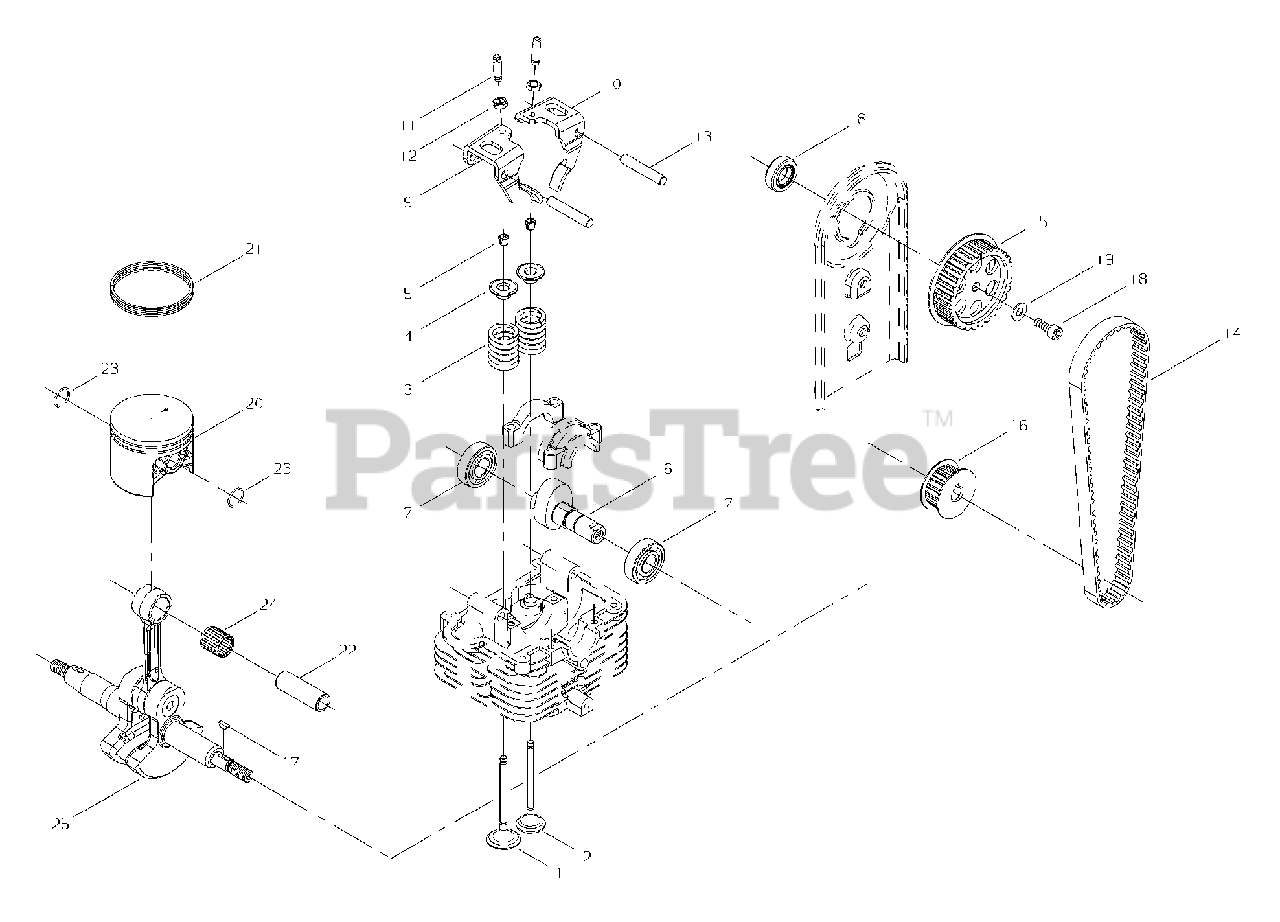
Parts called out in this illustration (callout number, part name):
1	VALVE, INTAKE
2	VALVE, EXHAUST
3	SPRING, VALVE
4	RETAINER, VALVE
5	KEEPER, VALVE
6	CAMSHAFT
7	BEARING, BALL 6001
8	SEAL, OIL 12
9	ARM, ROCKER
10	ARM, ROCKER
11	SCREW, ADJUSTER
12	NUT, ADJUSTER LOCK 5
13	SHAFT, CAM FOLLOWER 6
14	BELT
15	PULLEY, CAM
16	PULLEY, CRANK
17	KEY, WOODRUFF 3×10
18	BOLT 5×14
19	WASHER 5.3×10×1
20	PISTON
21	RING, PISTON
22	PIN, PISTON 12
23	RING, SNAP
24	BEARING, NEEDLE 12
25	CRANKSHAFT ASSY
